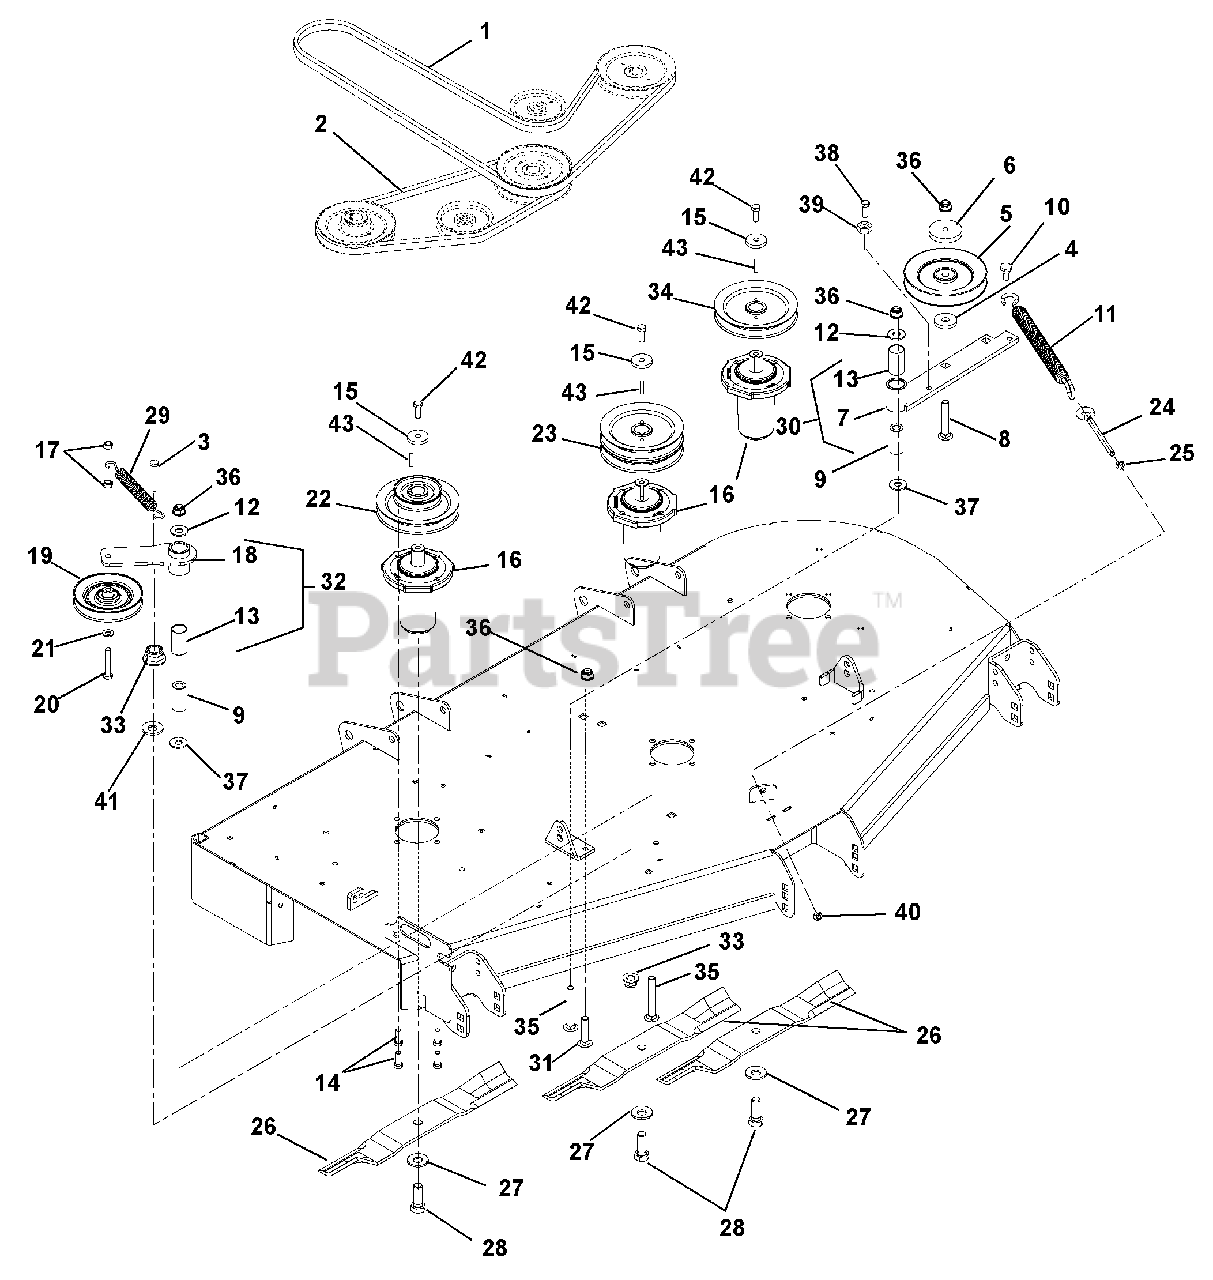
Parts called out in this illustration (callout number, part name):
1	HEX BELT, BB-WRAPPED
2	V-BELT, B-COGGED
3	@BLT-HEX .38-16X3.00 GR5 YWZC
4	BSHG, SPCR .502X.997X.50 PM
5	SHV, .50"ID X 6.00"OD V-IDLER
6	CAP, IDLER BEARING SEALING
7	WMT, IDLER ARM
8	@BLT-RDHDSQNK .50-13X3.00 G5YZ
9	BSHG, SPCR .502X.997X2.03 PM
10	BLT,SHLDR EP .38-16X.30 HEX YZ
11	SPRING, EXTENSION
12	@WSHR-FL-STL.563X1.38X.109YWZC
13	BSHG, 1.00 X 1.125 X 1.937
14	BLT-HEX .38-16X1.0 GR8 YZ EP30
15	RETAINER, SHEAVE
16	ASM, MAINT FREE SPINDLE
17	@NUT-LK-CTR .38-16 YWZC
18	WMT, IDLER ARM
19	IDLER, V-5.00"
20	@BLT-HEX .38-16X2.25 GR5 YWZC
21	@WSHR-FL-STL.406X.812X.065 YWZ
22	PULLEY, DBL-1"IDX6.75"&4.25"OD
22	PULLEY, DOUBLE-1"IDX3.50"&6.0
23	PULLEY, DOUBLE-1"ID X 6.75"OD
23	PULLEY, DOUBLE
24	BOLT, .38-16X4.50 .62 DIA EYE
25	NUT-HEX-JAM .375-16 YWZC
26	BLADE, 20.5"
26	BLADE, 18"
27	WSHR-BLVL .669X1.535X.138
28	BLT-HEX .62-18X1.75 GR8 YWZC
29	SPRING, EXTENSION
30	ASM, IDLER PIVOT ARM (PTO)
31	BLT-RDHDSHSQNKFT.50-13X1.50 G5
32	ASM, IDLER ARM (DECK)
33	@NUT-SPNLK-FLG .375-16 YWZC
34	PULLEY, V-1" ID X 6.75" OD
34	PULLEY, SINGLE-1"ID X 6" OD
35	@BLT-RDHDSQNK .50-13X3.50 G5YZ
36	@NUT-LK-NYL-FLG .50-13 YWZC
37	WSHR-FLT .640X1.75X.250
38	@BLT-HEX .38-16X2.75 GR5 YWZC
39	@NUT-HEX .38-16 YWZC
40	@NUT-LK-CTR-JAM .375-16 YWZC
41	WSHR-FL-STL .406X1.375X.135 YZ
42	BLT-HEX .38-16X2.75 GR8 YWZC
43	KEY, SQ .25X.25X1.00 RC 40-50
